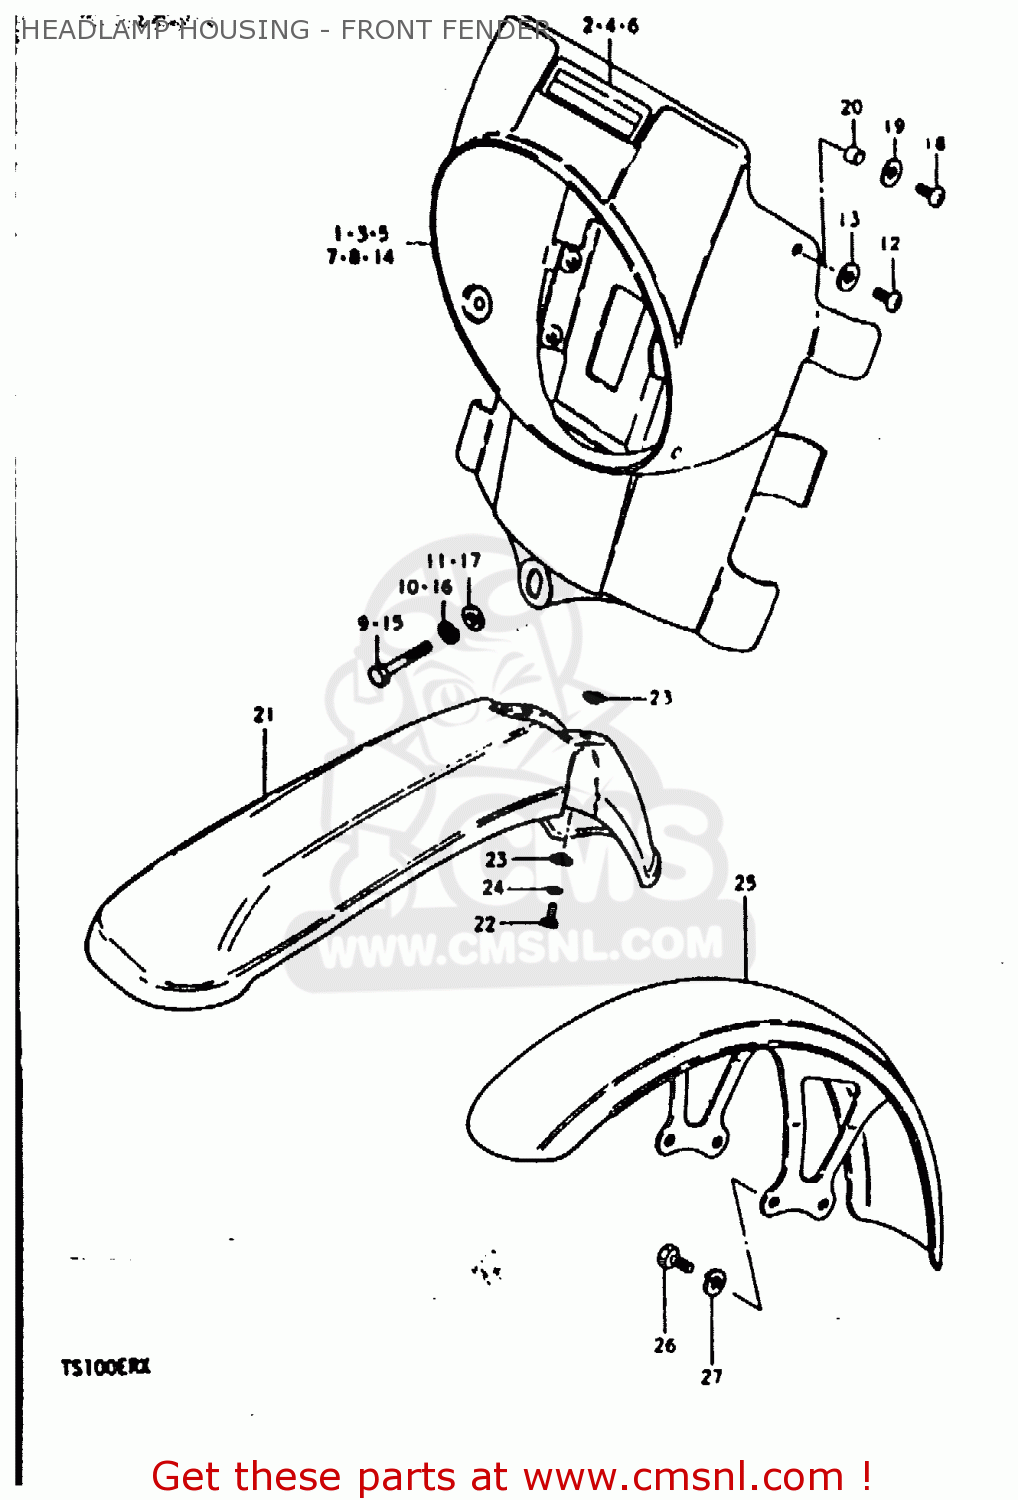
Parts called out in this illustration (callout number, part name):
1	HOUSING, HEADLAMP (RED)
2	TAPE, HOUSING
3	HOUSING,HEADLAMP
4	TAPE, HOUSING
5	HOUSING, HEADLAMP (WHITE)
6	TAPE, HOUSING
7	HOUSING, HEADLAMP (BLUE)
8	HOUSING, HEADLAMP (YELLOW)
9	BOLT
10	LOCK WASHER
11	WASHER
12	SCREW
13	WASHER (5.5X16X1.2)
14	HOUSING,HEADLAMP
15	BOLT
16	LOCK WASHER
17	WASHER
18	SCREW
19	WASHER (5.5X18X1.6)
20	SPACER (5.5X8X4)
21	FENDER,FRONT
22	BOLT, UPPER
23	SPACER
24	LOCK WASHER
